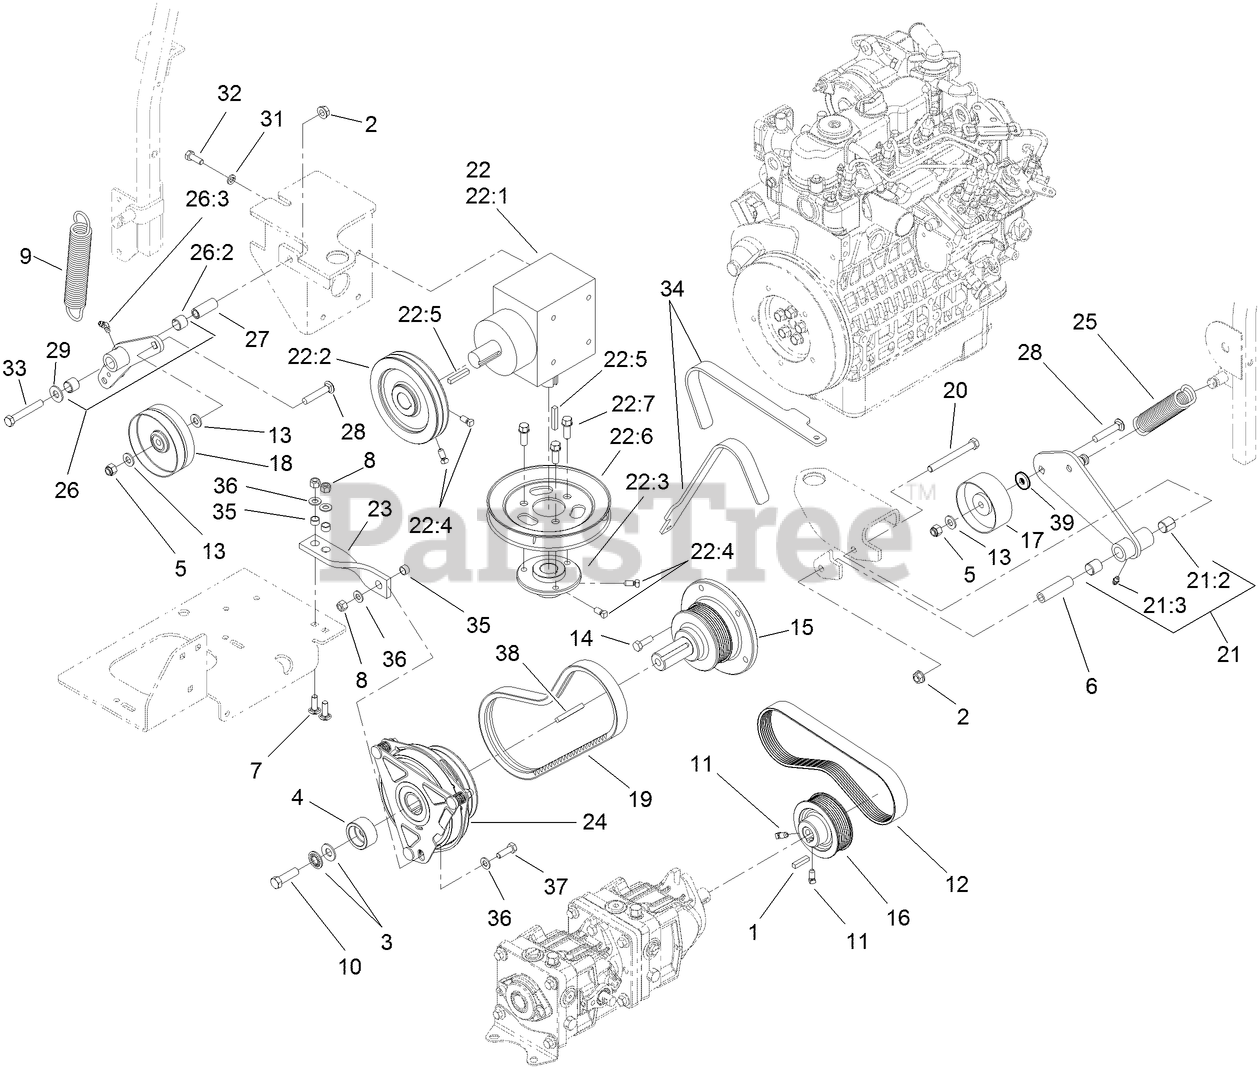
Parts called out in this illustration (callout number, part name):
2	NUT-HHF, WHIZ
3	WASHER-SPRING
4	RETAINER-CLUTCH
5	NUT-LOCK, NI
6	BUSHING-PIVOT, IDLER
7	SCREW-CARR
8	NUT-LOCK, NI
9	SPRING-EXTENSION
10	SCREW-HH
11	SCREW-SET
12	BELT-V
13	WASHER-FLAT
14	SCREW-HH
15	SHAFT-STUB
16	PULLEY
17	PULLEY-FLAT
18	PULLEY-FLAT
19	BELT-V
20	SCREW-HH
21	PUMP IDLER ARM ASM
21:2	SLEEVE-BEARING
21:3	FITTING-GREASE
22	GEARBOX ASM
22:1	GEARBOX-90 DEG
22:2	PULLEY
22:3	HUB-PULLEY
22:4	SCREW-SET
22:5	KEY-SQUARE
22:6	PULLEY-B SECTION
22:7	SCREW-HWH
23	STRAP-STOP, CLUTCH
24	CLUTCH-MAGNETIC
25	SPRING-EXTENSION
26	GEARBOX IDLER ASM (W/BEARINGS)
26:2	SLEEVE-BEARING
26:3	FITTING-GREASE
27	BUSHING
28	SCREW-CARR
29	WASHER-FLAT
31	WASHER-LOCK
32	SCREW-HH
33	SCREW-HH
34	TOOL-ALIGNMENT, PULLEY
35	SPACER
36	WASHER-PLAIN
37	SCREW-HH
38	KEY-SQUARE
39	WASHER
